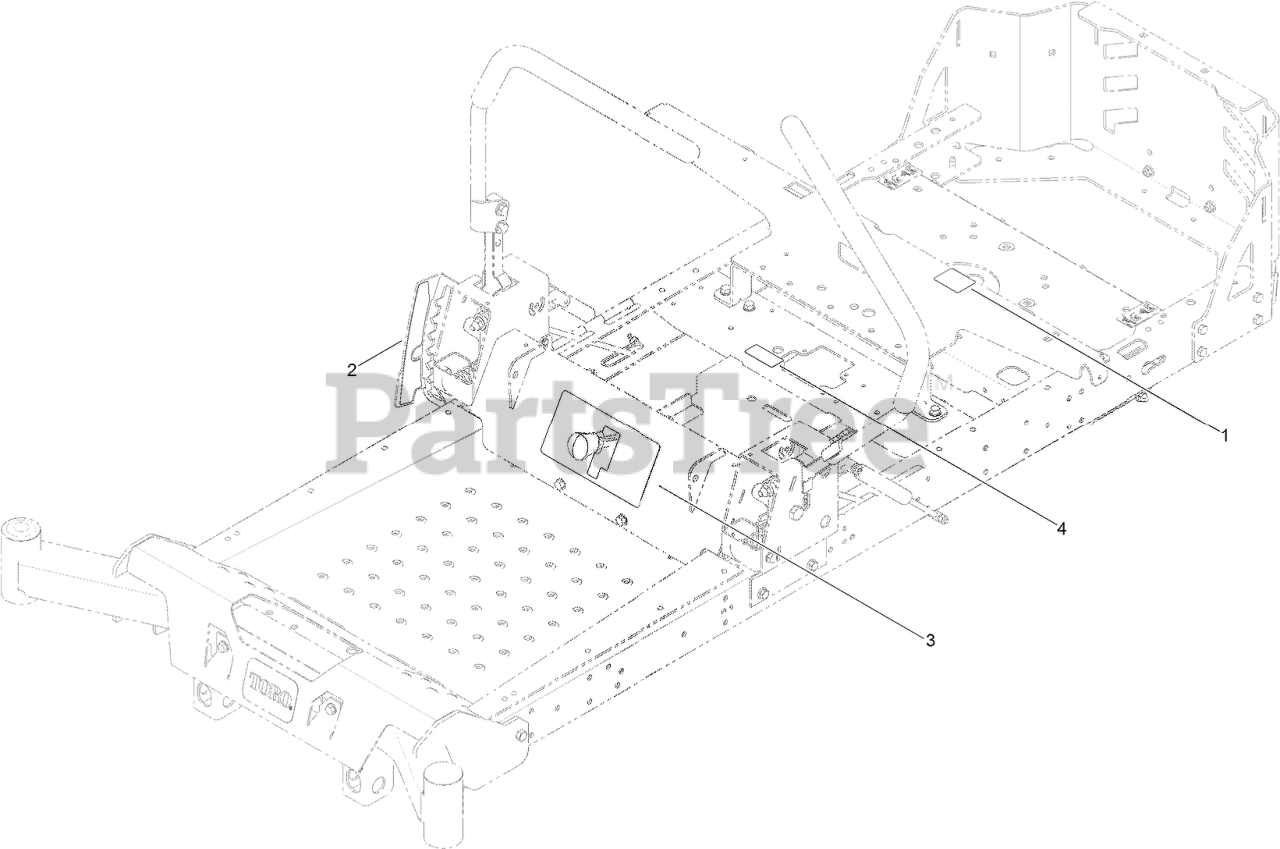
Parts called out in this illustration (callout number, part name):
1	DECAL-MAINTENANCE
2	DECAL-HOC
3	DECAL-CONTROL, SPEED
4	DECAL-LOCATION, SERVICE DEALER
